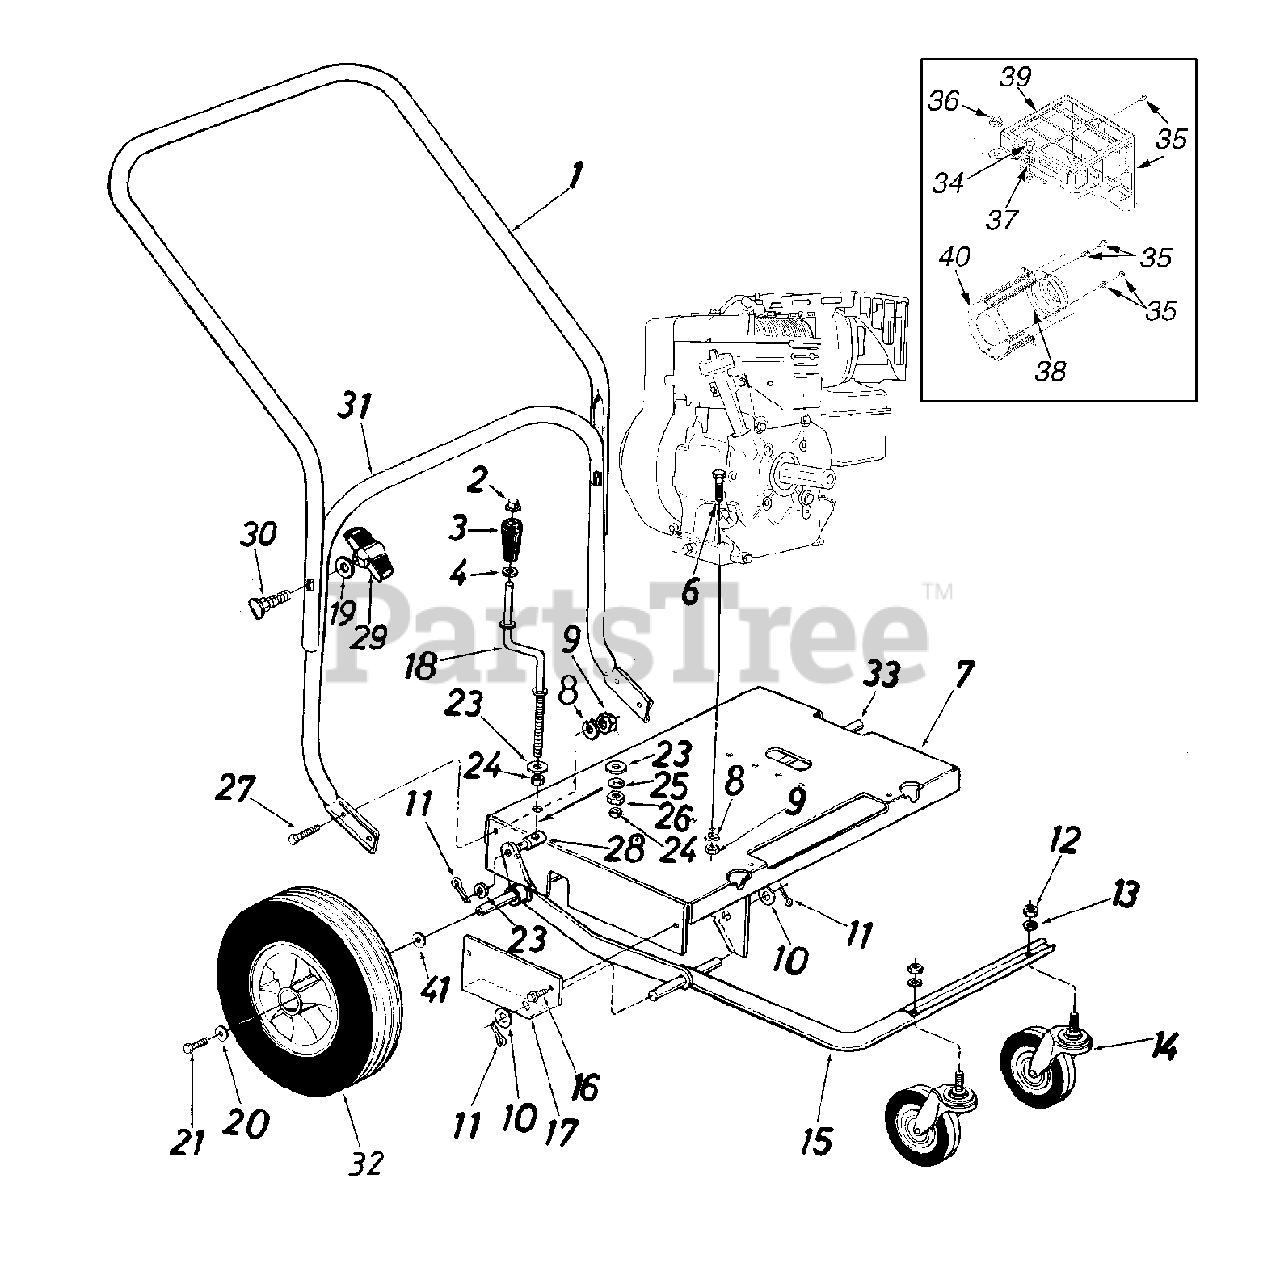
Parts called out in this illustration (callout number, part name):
2	Push Nut 3/8
3	Crank Knob
4	Flat Washer .385 ID x .62 OD
6	Hex Bolt 5/16-18 x 1.50
9	Hex Nut 5/16-18
10	Flat Washer .63 ID x 1.25
11	Cotter Pin
12	Hex Nut 1/2-13
13	Lock Washer 1/2
14	Swivel Caster Wheel 5" Dia x 1.25
19	Saddle Washer .32 ID x .93 OD
20	Flat Washer .34 ID x .87 OD
21	Hex Lock Bolt 5/16-24 x .64
23	Flat Washer .38 ID x .57 OD
24	Spacer .382 ID x .50 OD x .180Lg
25	Lock Washer 3/8 ID
26	Hex Nut 3/8-8
27	Hex Bolt 5/16-18 x .75
28	Ferrule
29	Hand Knob
30	Carriage Bolt 5/16-18 x 2.0
33	Rear Axle
34	Self Tap Screw 1/4-20 x .5
35	Screw 8-18 x .375
36	Hex Lock Nut 5/16-18
37	Lock Washer
38	Deflector
39	Muffler Guard
40	Muffler Guard Bracket
41	Flat Washer
